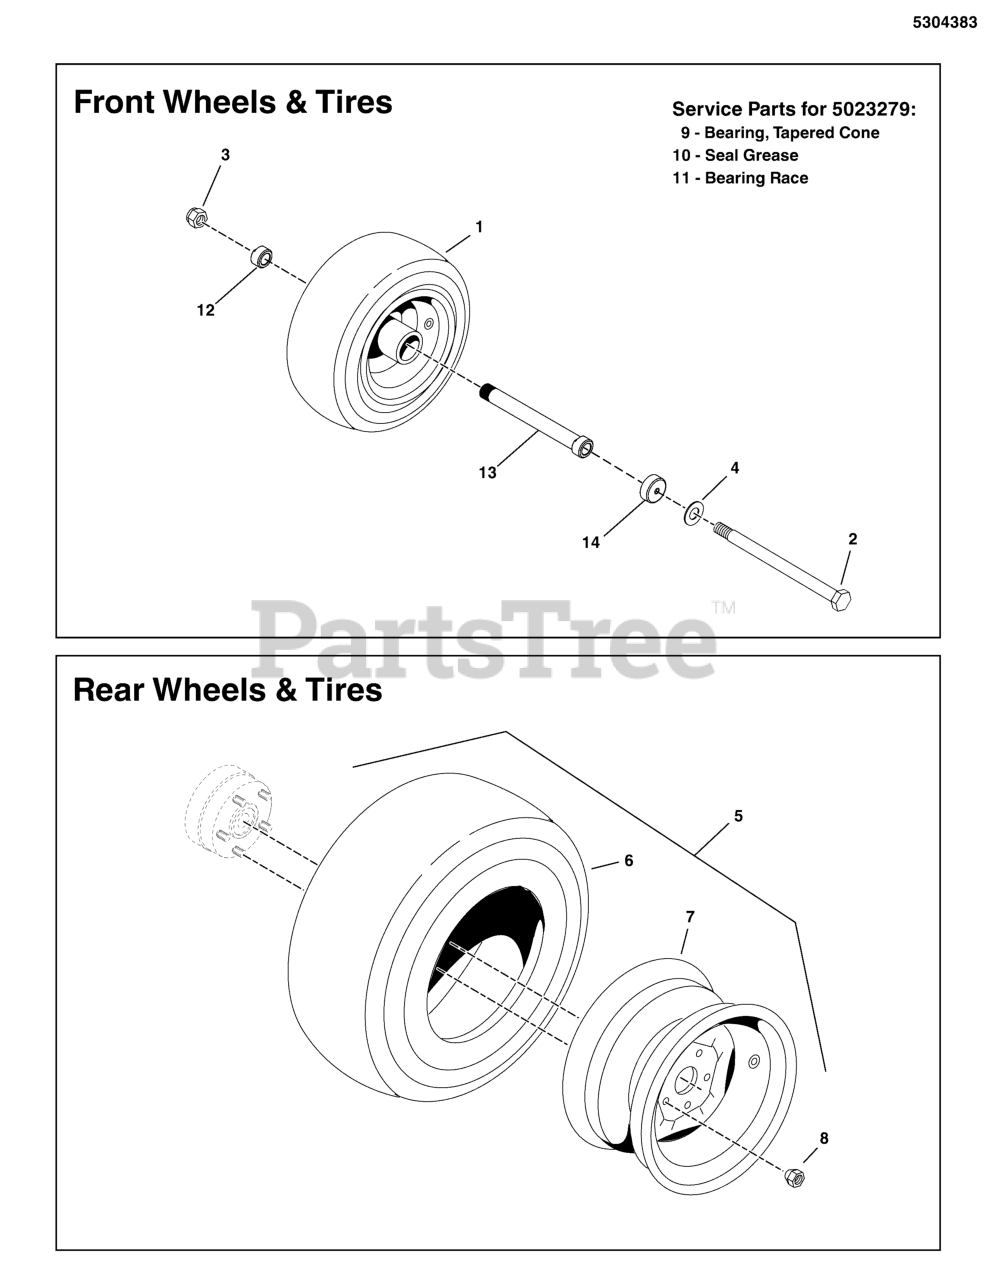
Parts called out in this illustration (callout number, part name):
1	TIRE ASSM, 13 X 6.5 - 6, FF / TB
2	BOLT, 1/2-13 X 9" GD5 YZ
3	NUT, Hex Flange, Nylock, 1/2-13
4	WASHER, 1/2 SAE
5	TIRE/WHEEL ASM, 24X9.50-12, TURF SMART
5	TIRE WHEEL ASM, 24X9.50-12, TURF MASTER
6	TIRE, 24 X 9.50-12 PR TURF SMART (SV)
6	TIRE ONLY, 24X9.50-12, TURF MASTER
7	WHEEL, 12 X 7, 5/4.5, 1.13 OFFSET (SV)
8	NUT, 1/2-20, FOR WHEEL BOLT SILVER
9	BEARING, Tapered Roller
10	SEAL, GREASE
11	BEARING, RACE
12	NUT, BEARING ADJUSTER, AXLE
13	BEARING ADJUSTER, SPACER, 7.062 LG
14	DEBRIS, COVER, CASTER WHEELS
